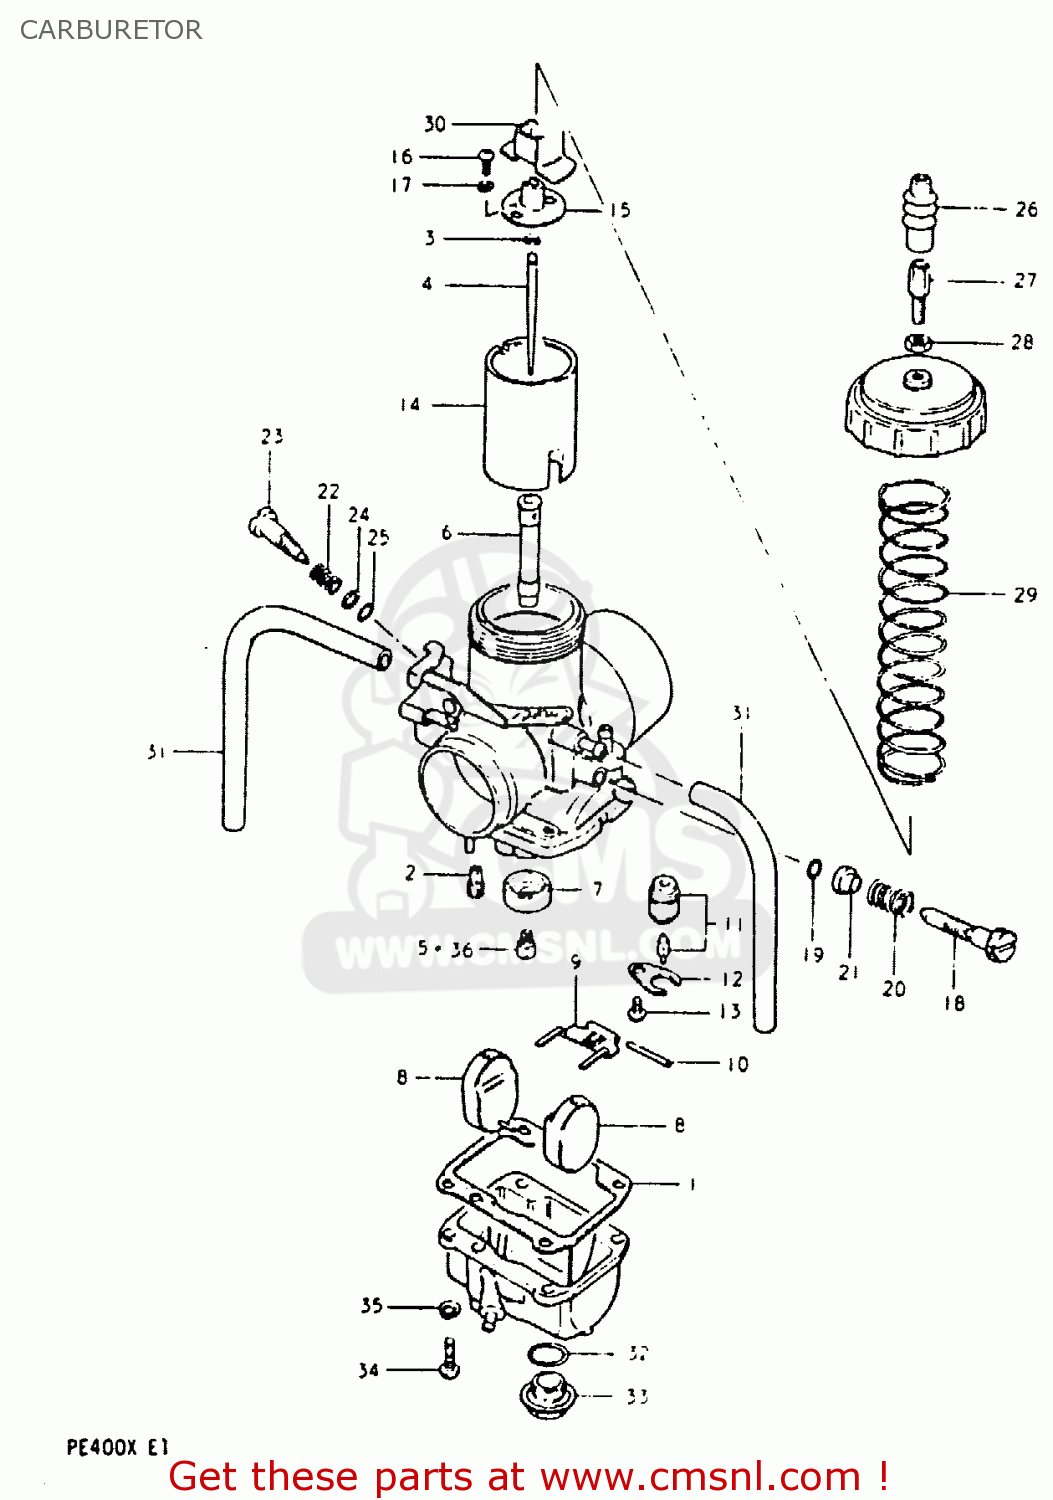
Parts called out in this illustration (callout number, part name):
1	GASKET,FLOAT CAHMBER (NAS)
2	JET,PILOT
3	CLIP
4	NEEDLE JET
5	JET
6	JET,NEEDLE
7	RING,MAIN JET FIXING
8	FLOAT
9	ARM,FLOAT
10	PIN,FLOAT
11	VALVE ASSEMBLY,NEEDLE
12	PLATE
13	SCREW
14	VALVE,THROTTLE
15	CONNECTOR
16	SCREW
17	LOCK WASHER
18	SCREW,THROTTLE STOP
19	O-RING
20	SPRING,THROTTLE STOP
21	COVER
22	SPRING
23	SCREW,PILOT AIR
24	WASHER,PILOT AIR SCREW
25	O RING
26	CAP,CABLE ADJUSTER
27	ADJUSTER,CABLE
28	NUT
29	SPRING,THROTTLE VALVE RETURN
30	COVER,HOLDER
31	HOSE
32	O-RING
33	PLUG
34	SCREW
35	LOCK WASHER
36	JET
